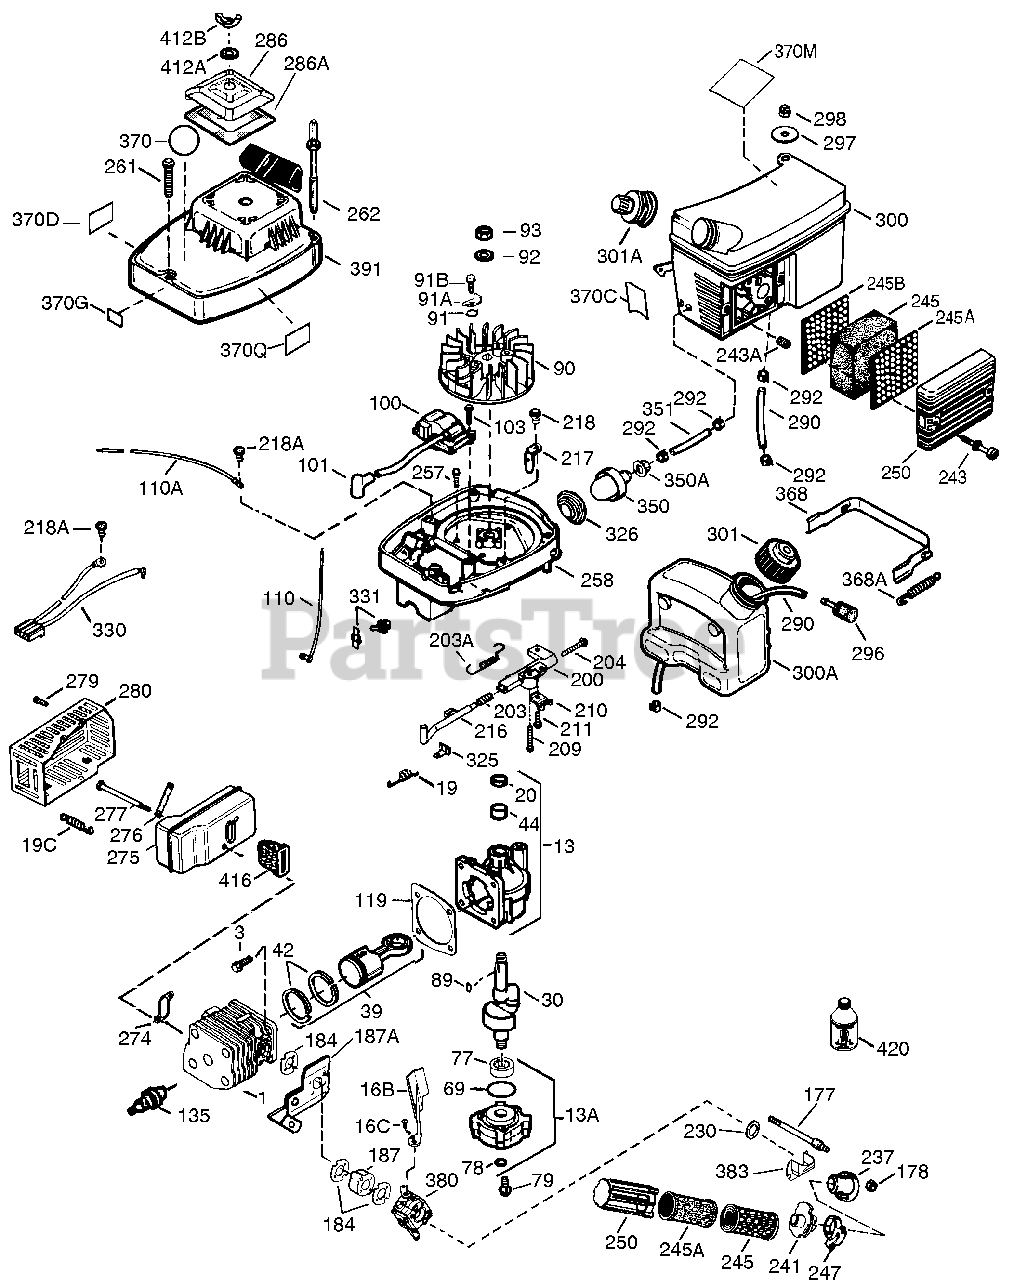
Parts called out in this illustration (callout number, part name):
1	"Cylinder (Incl. 119, 184, 187 & 187A)
3	Screw, T-30, 1/4-20 x 43/64"
13	Crankcase Ass'y. (Incl. 20, 44 & 69)
13A	Crankcase Cover
16B	Air Vane
16C	Screw, T-8, 3-48 x 7/32"
19	Governor Spring
19C	Heat Shield Spring
20	Oil Seal
30	Crankshaft
39	Piston & Rod Assembly (Incl. 42)
42	Ring Set
44	Cartridge Bearing
77	Ball Bearing
78	Oil Seal
79	Screw, 1/4-20 x 3/4"
89	Flywheel Key
90	Flywheel
91	Pawl Spring
91A	Starter Pawl
91B	Screw, 12-24 x 11/64"
92	Belleville Washer
93	Flywheel Nut
100	Solid State Ignition (Incl. 101)
101	Spark Plug Cover
103	Screw, T-15, 10-24 x 15/16"
110	Ground Wire
119	Cylinder Gasket
135	Resistor Spark Plug (RCJ8Y)
177	Carburetor Mounting Stud
178	Lock Nut, 10-24
184	Carburetor Gasket
187A	Air Baffle (Incl. 184 & 187)
200	Speed Control Body
204	Screw, T-15, 8-32 x 1"
209	Screw, T-15, 8-32 x 1"
210	Conduit Clip
211	Screw, T-15, 10-24 x 21/32"
216	R.P.M. Adjusting Lever
243	Screw, 10-32 x 29/32"
243A	Thread Insert
245	Air Filter (Poly) (also available in Packaged Part #740097 (incl. 450255 & 450257))
245A	Air Filter
245B	Air Filter (Flocked Screen)
250	Air Cleaner Cover
257	Screw, 10-24 x 1/2"
258	Housing Base
261	Screw, 8-32 x 1-9/16"
274	Exhaust Gasket
275	Muffler (Incl. 274 & 277)
277	Screw, 1/4-20 x 2.409"
279	Screw, 8-32 x 25/64"
280	Heat Shield
290	Fuel Line
292	Fuel Line Clamp
298	Lock Nut, 8-32
300	Fuel Tank Incl. 290, 292, 298, 301 &3 70C
301	Fuel Cap
326	Blower Housing Plug
331	Toggle Switch
370	Fuel Mix Decal
370C	Choke Decal
370Q	Emissions Decal
380	Carburetor (Incl. 184)
391	Recoil Starter & Housing Assembly
420	2-Cycle Oil with Fuel Stabilizer - 8 oz.
